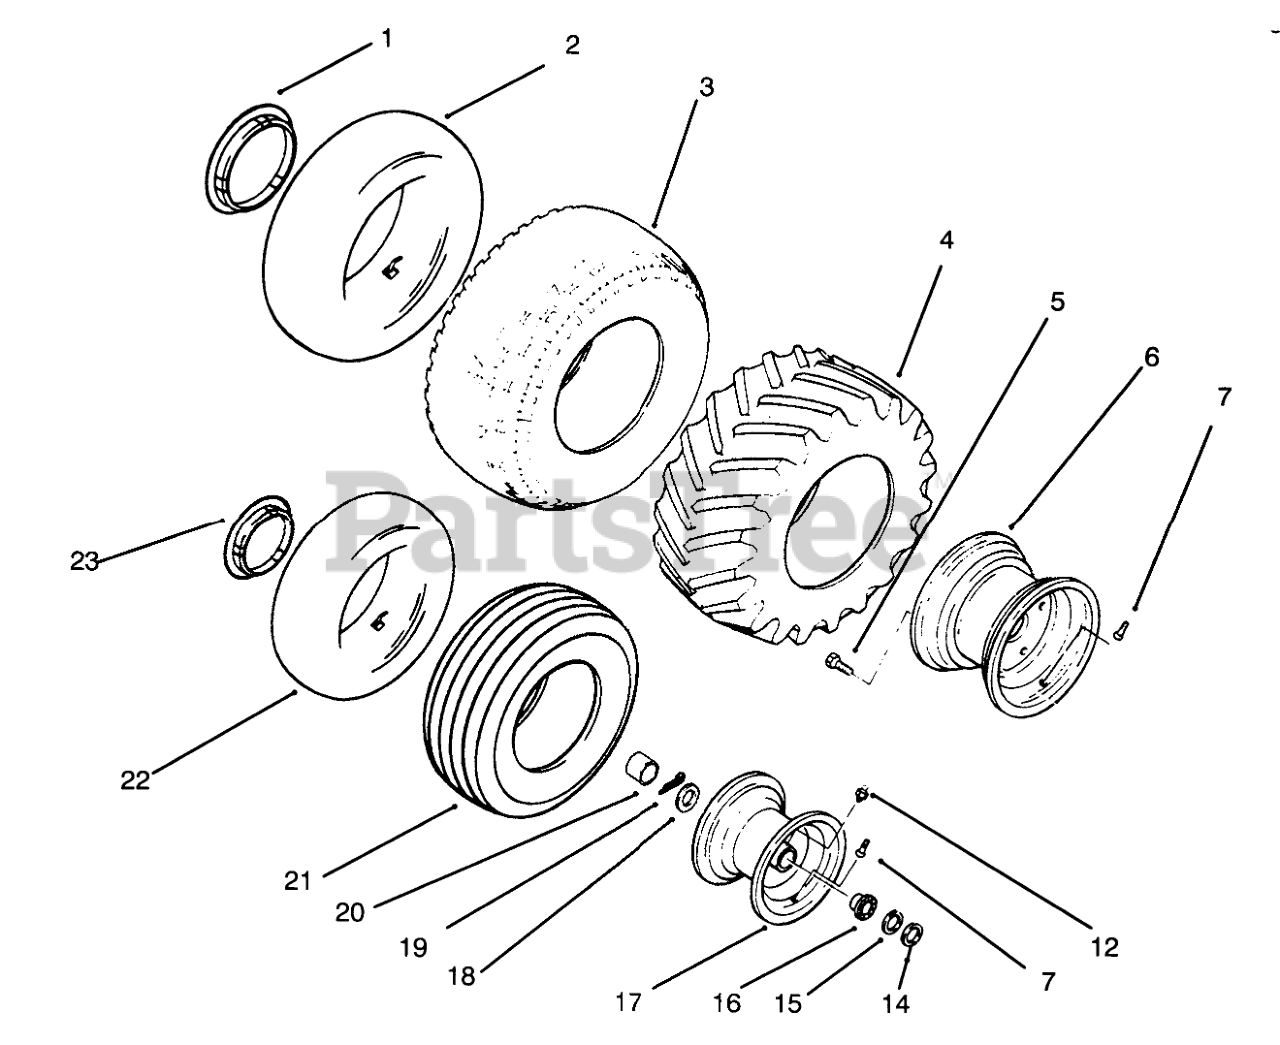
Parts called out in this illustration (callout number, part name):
1	12"-HUB CAP LOGO
2	Tube-Rear (Opt.)
3	TIRE
4	Tire-Cleat, Rear
5	BOLT-LUG
6	WHEEL
7	VALVE
12	ZERK-GREASE
14	WASHER-SHIM
15	WASHER
16	BEARING-WHEEL
17	Rim-Front
18	Washer-Special Hub Cap
19	PIN-COTTER
20	HUB CAP-FLAT BLACK
21	Tire (16 x 6.5-8) 2-Ply -2 Wheel Axel
23	6"-HUB CAP LOGO
